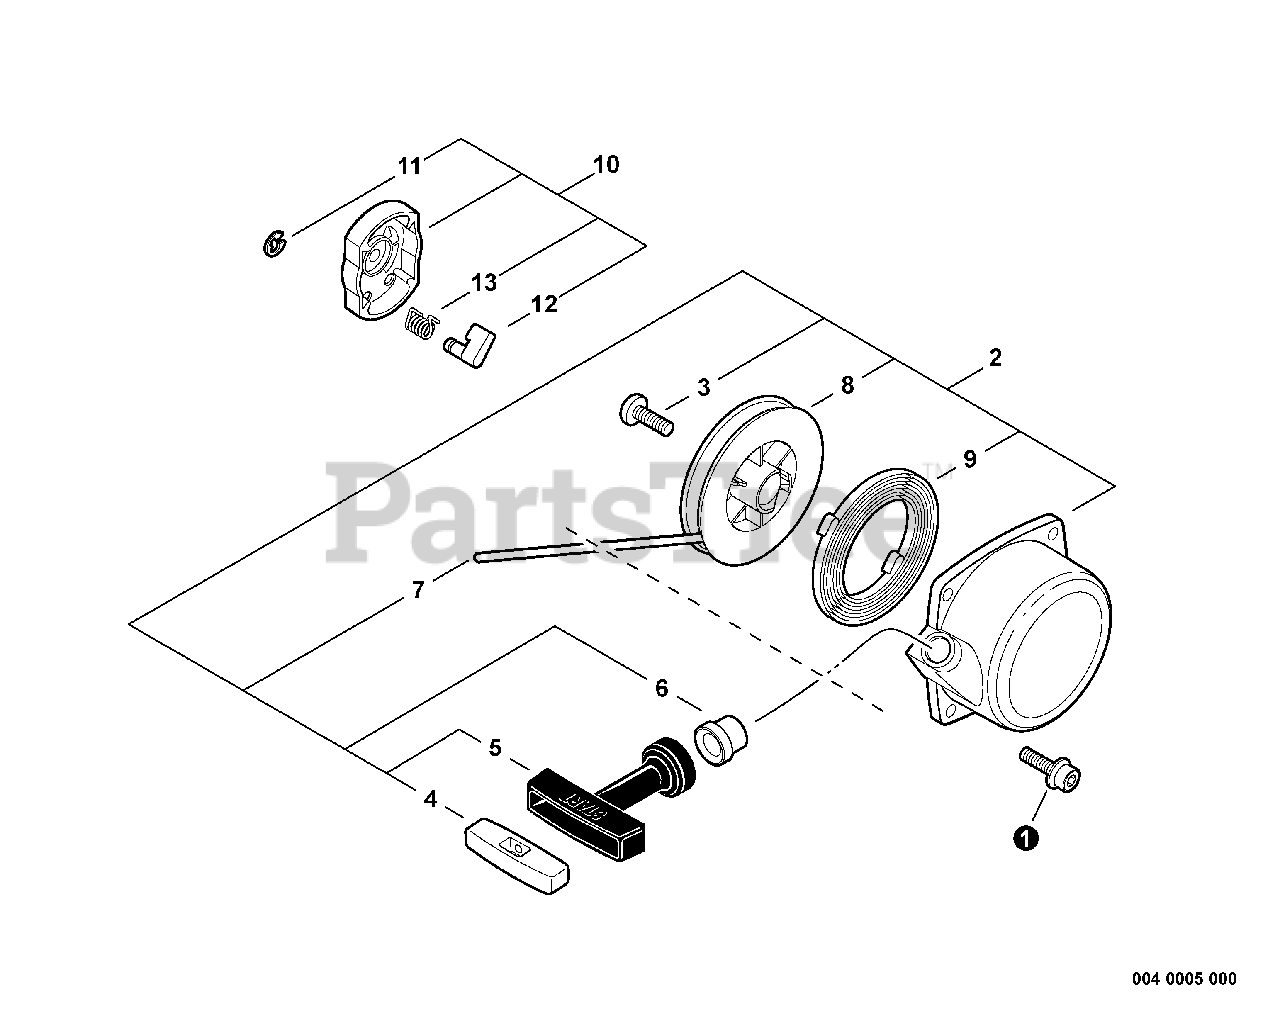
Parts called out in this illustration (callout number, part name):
1	BOLT 5×14
2	STARTER ASSY
4	RETAINER, ROPE
5	GRIP, STARTER
6	GUIDE, ROPE
7	ROPE, STARTER 3.8×1150
8	REEL, ROPE
9	SPRING, RECOIL
10	PAWL ASSY, STARTER
11	E-RING 4
12	PAWL, STARTER
13	SPRING, RETURN
